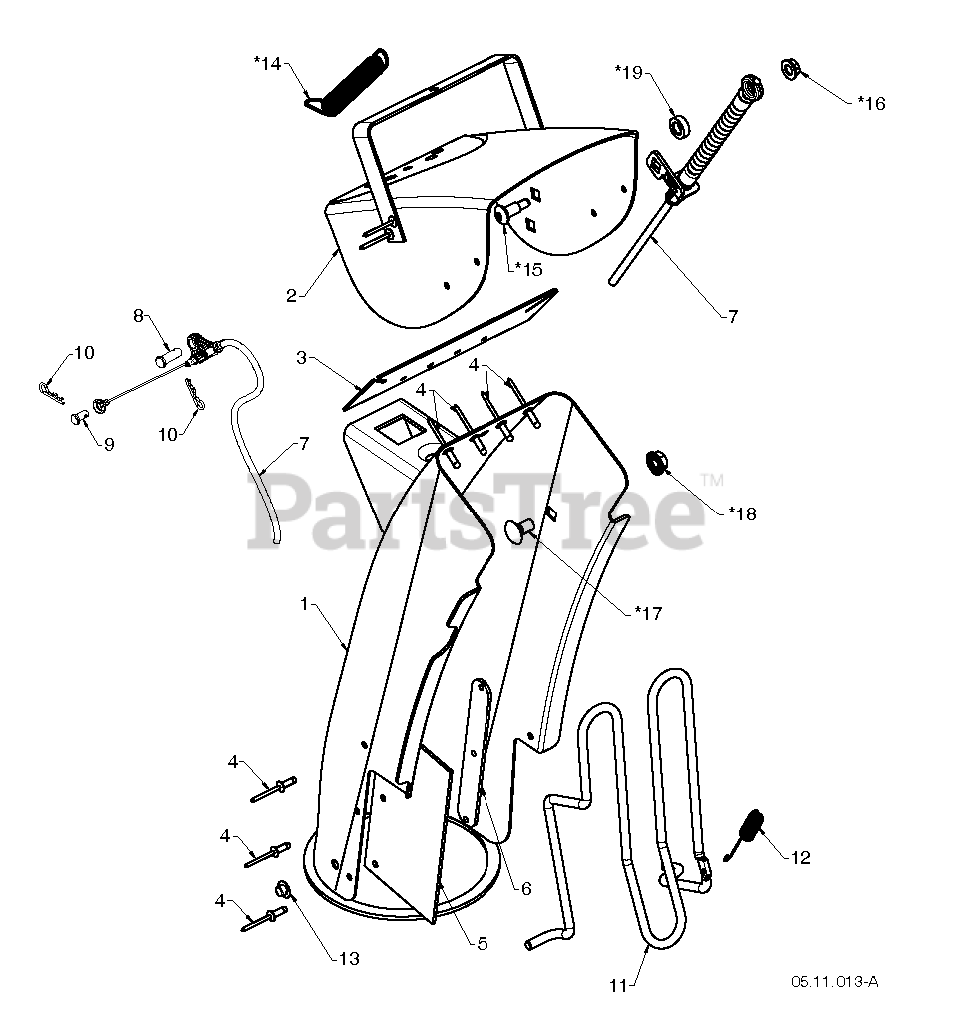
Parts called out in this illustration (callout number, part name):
1	ASM.CHUTE/DEFLECTOR.668
8	PIN CLEVIS 5/16X.875
9	PIN CLEVIS .25 X .31
10	HAIRPIN.SOFT.ZINC.059X1.125
11	GUARD ROD CHUTE GUARD SHORT CL
12	SPRING.CHUTE.GUARD
13	PAL NUT PM
